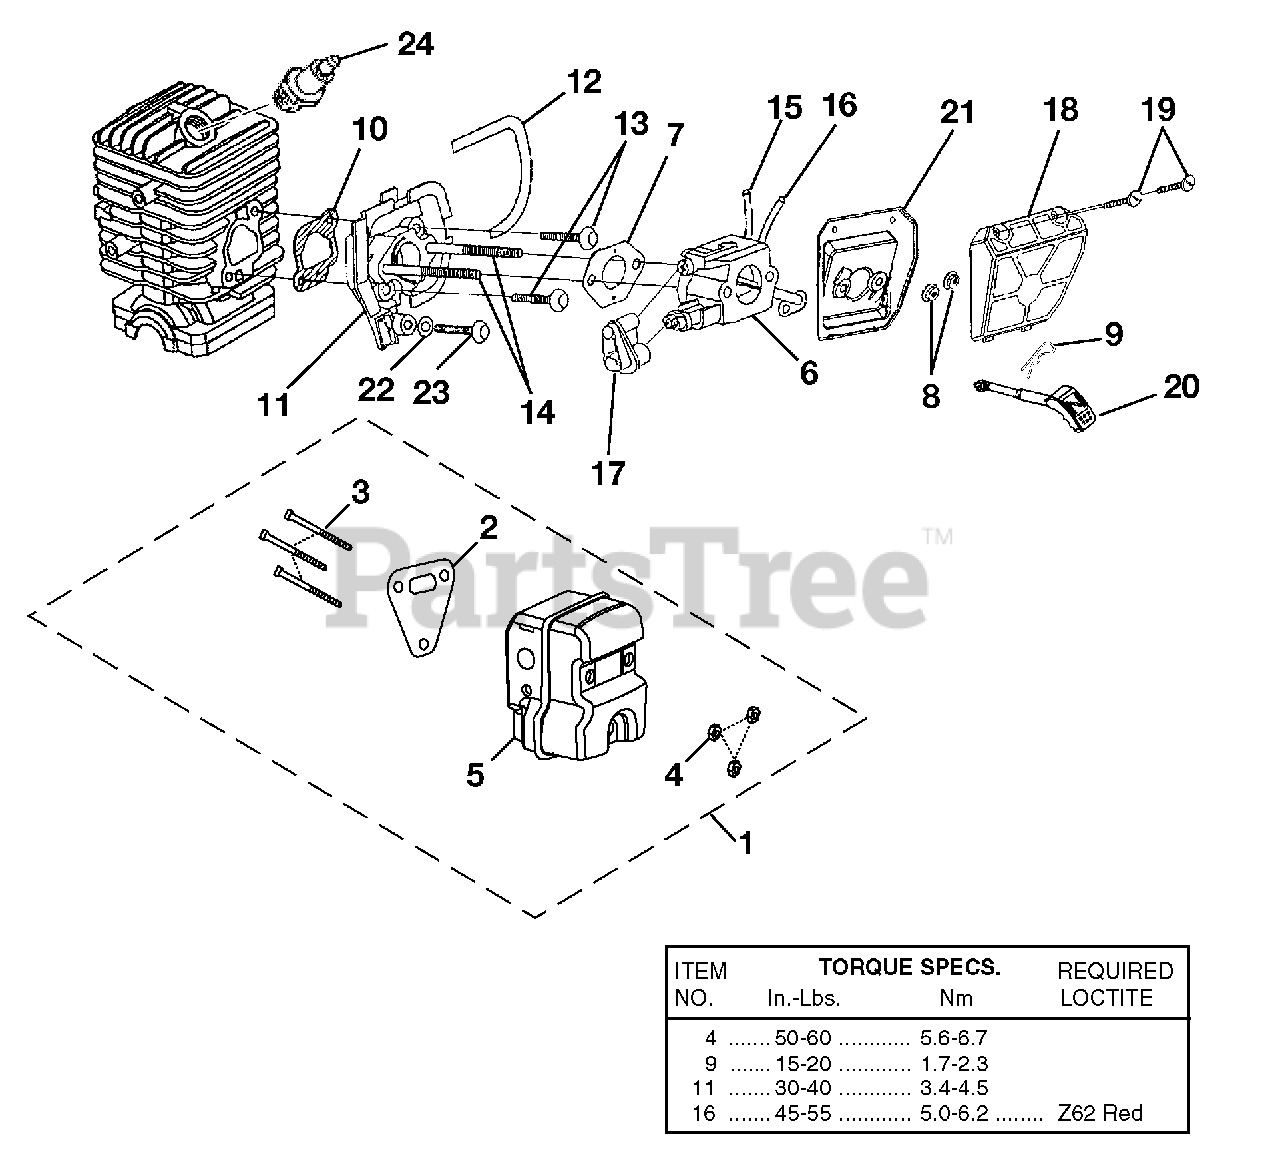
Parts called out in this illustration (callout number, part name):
1	Exhaust Assembly
2	Muffler Gasket
3	Screw-Square Hd.
4	Nut-Locking Hex (10-32)
5	Muffler
6	Carburetor Assembly
7	Carburetor Gasket
8	Flange Nut (10-24)
9	Spring Clip (Choke Rod)
10	Gasket, Heat Dam
11	Carburetor Spacer
12	Seal, Heat Dam
13	Screw, Truss Hd.Taptite (10-24 x 7/8")
14	Screw, Carburetor
15	Fuel Line (Tankto Carburetor 81/2")
16	Fuel Line (Carburetorto Purge Bulb 4")
17	Carburetor Grommet
18	Air Filter Cover
19	Screw-Slotted Pan Hd. (8-16 x 5/8")
20	Rod, Choke
21	Air Filter Plate
22	Flat Washer
23	Screw(10-14x 1/2 in.)
24	Spark Plug
